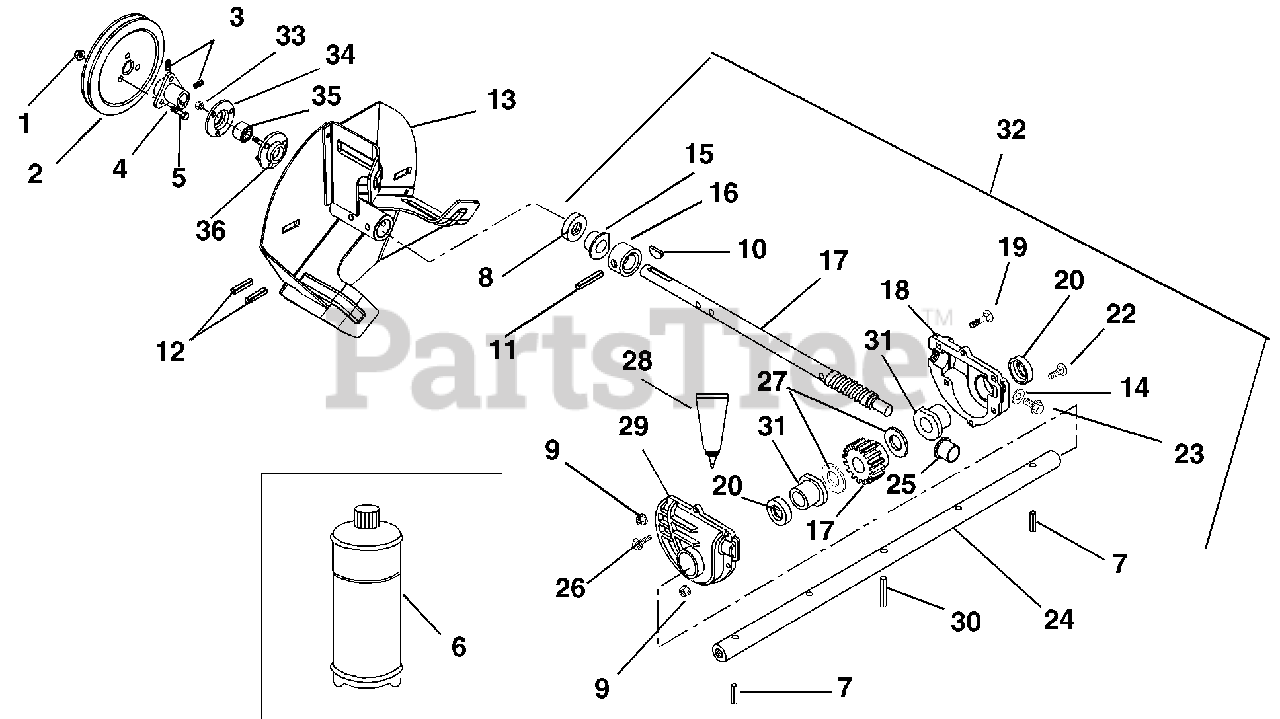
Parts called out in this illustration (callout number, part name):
1	@NUT-SPNLK-FLG .312-18 YWZC
2	PLY-V 8.50 X 1.25 3BLT
3	SCR-SET .31-18X.38 SKHCUPDL
4	HUB ASSEMBLY
5	BLT-SERRDHD SL .31-18X.75 YZ
6	ARIENS 16 OZ.BOTTLE OF L2 LUBE
7	PIN-ROLL .188X1.50
8	SEAL-OIL .750X1.375X.250
9	@NUT-SPNLK-FLG .25-20 YWZC
10	KEY-WDRF .188X.875X.375 SAE11
11	PIN-GRV .188X1.25 TP A
12	PIN-ROLL .250X1.75
13	IMPELLER - .75 ID X 12" OD
14	WSHR-FIBER .437X.656X.032
15	BSHG-FLG .750X1.000X.750X1.250
16	THRUST COLLAR
17	SHAFT & WORM GEAR ASSEMBLY
18	CASE, GEAR-LH-LARGE BORE-ALUM.
19	@BLT-RDHDSQNK .25-20X1.25 G5YZ
20	SEAL-OIL 1.000X1.375X.250
22	@BLT-RDHDSQNK .25-20X1.00 G5YZ
23	@SCR-TAP .38-16X.50 HWH TR YWZ
24	SHAFT, RAKE - 24"
25	BSHG-FLG .502X1X.750
26	SCR-TAP 10-24X.75 HWH TR YWZC
27	WSHR-HRD-THRS 1.007X1.542X.062
28	LOCTITE 518 GASKET--6ML TUBE
29	CASE, GEAR-RH-LARGE BORE-ALUM.
30	PIN-GRV .313X1.44 TP C
31	BSHG-FLG 1.00X1.12
32	GEAR CASE - ALUMINUM - 24"
33	@NUT-LK-CTR .25-20 YWZC
34	BEARING FLANGE
35	BRG-BALL .750X1.750X.50
36	BEARING FLANGE
